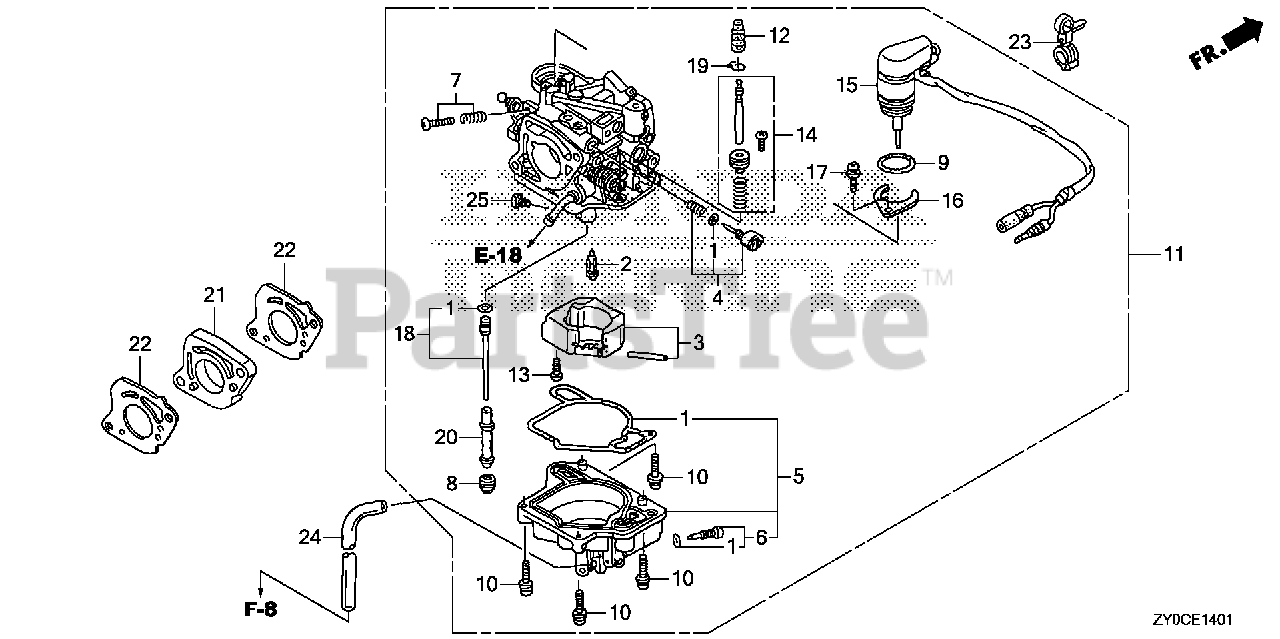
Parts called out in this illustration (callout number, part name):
1	GASKET SET
2	VALVE SET, FLOAT
5	CHAMBER SET, FLOAT
6	SCREW SET, DRAIN (CARBURETOR NO.)
7	SCREW SET
8	SCREW, PLUG
9	O-RING, BYSTARTER
10	SCREW-WASHER
11	CARBURETOR ASSY. (BJ08B A)
13	SCREW, PAN
14	PLUNGER SET, ACCELERATOR PUMP
15	BYSTARTER ASSY., AUTO
16	PLATE, SETTING
17	SCREW-WASHER
18	JET SET (#55)
19	CLIP, TUBE
20	NOZZLE, MAIN
21	INSULATOR, CARBURETOR
22	GASKET, CARBURETOR
23	CLIP, TUBE (135MM) (BLACK)
24	BULK HOSE, VINYL (4X7X8000) (95003-07(95003-07001-60M) (CARBURETOR NO.)
25	JET, MAIN (#120) (CARBURETOR NO.)
25	JET, MAIN (#122)
25	JET, MAIN (#125)
25	JET, MAIN (#128)
